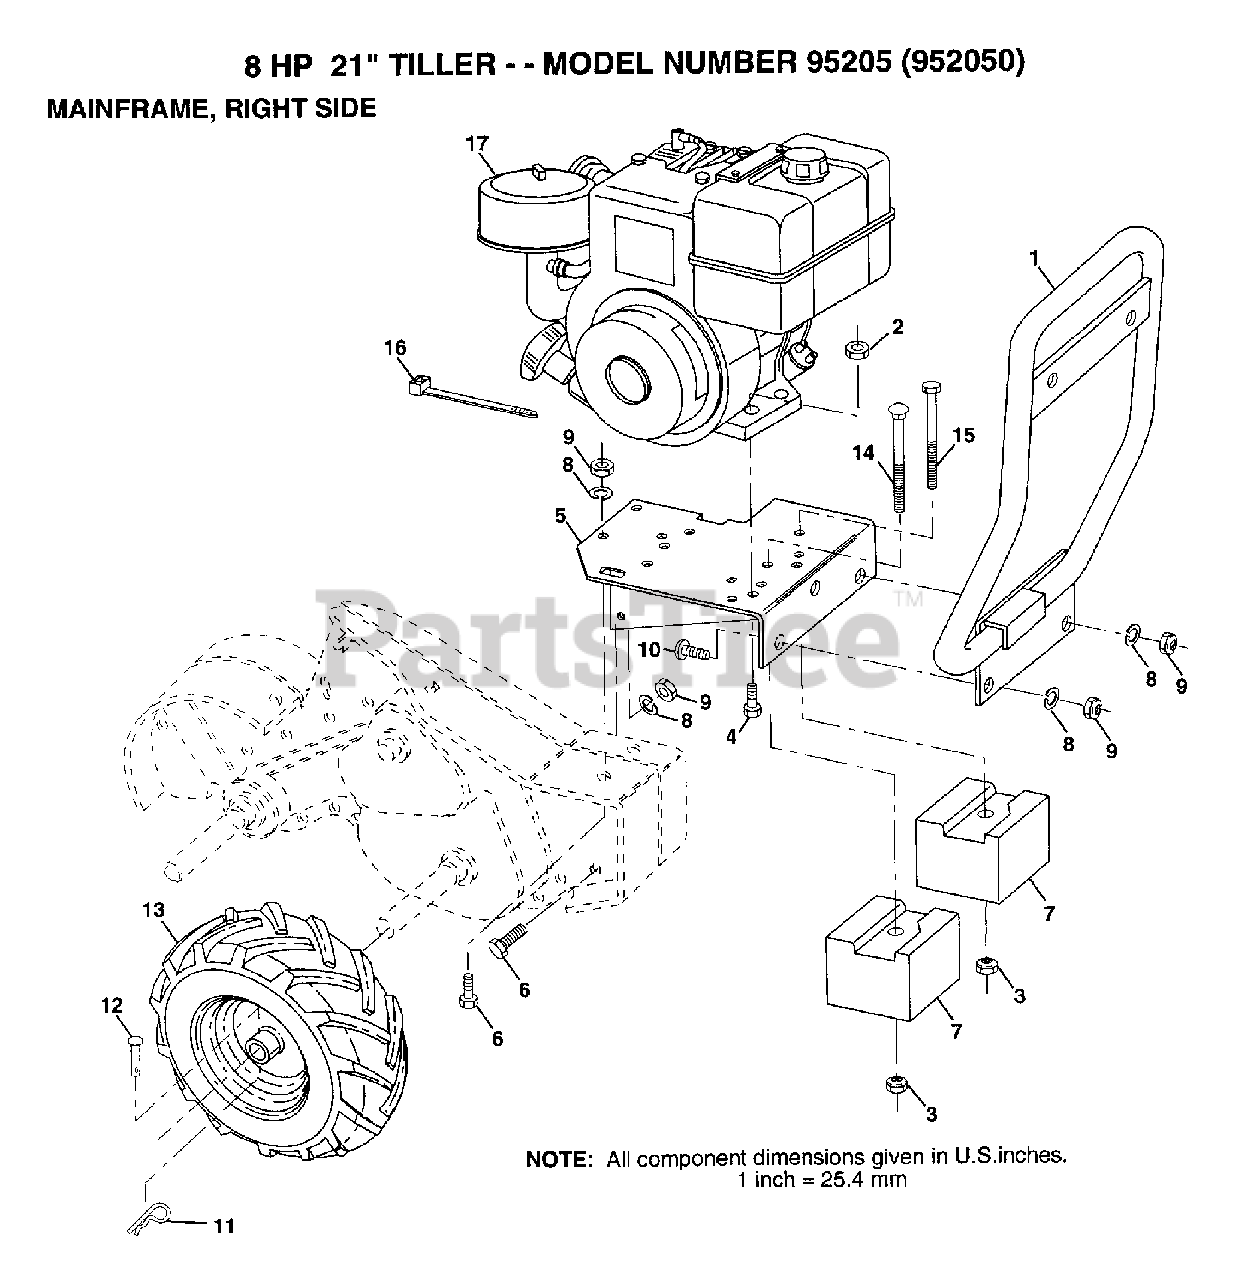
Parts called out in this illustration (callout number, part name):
1	BUMPER.ASM
4	BOLT
5	"ASM. ENGINE, BASE"
6	BOLT
7	COUNTERWEIGHT CRT
8	LOCKWASHER
9	NUT.HEX.3/8-16UNC
11	SPRING.RETAINER
12	RIVET.PAN HD.1.75
13	TIRE TI
14	BOLT CRT
15	BOLT.3/8-16X4.5
16	TIE CABLE CRT
